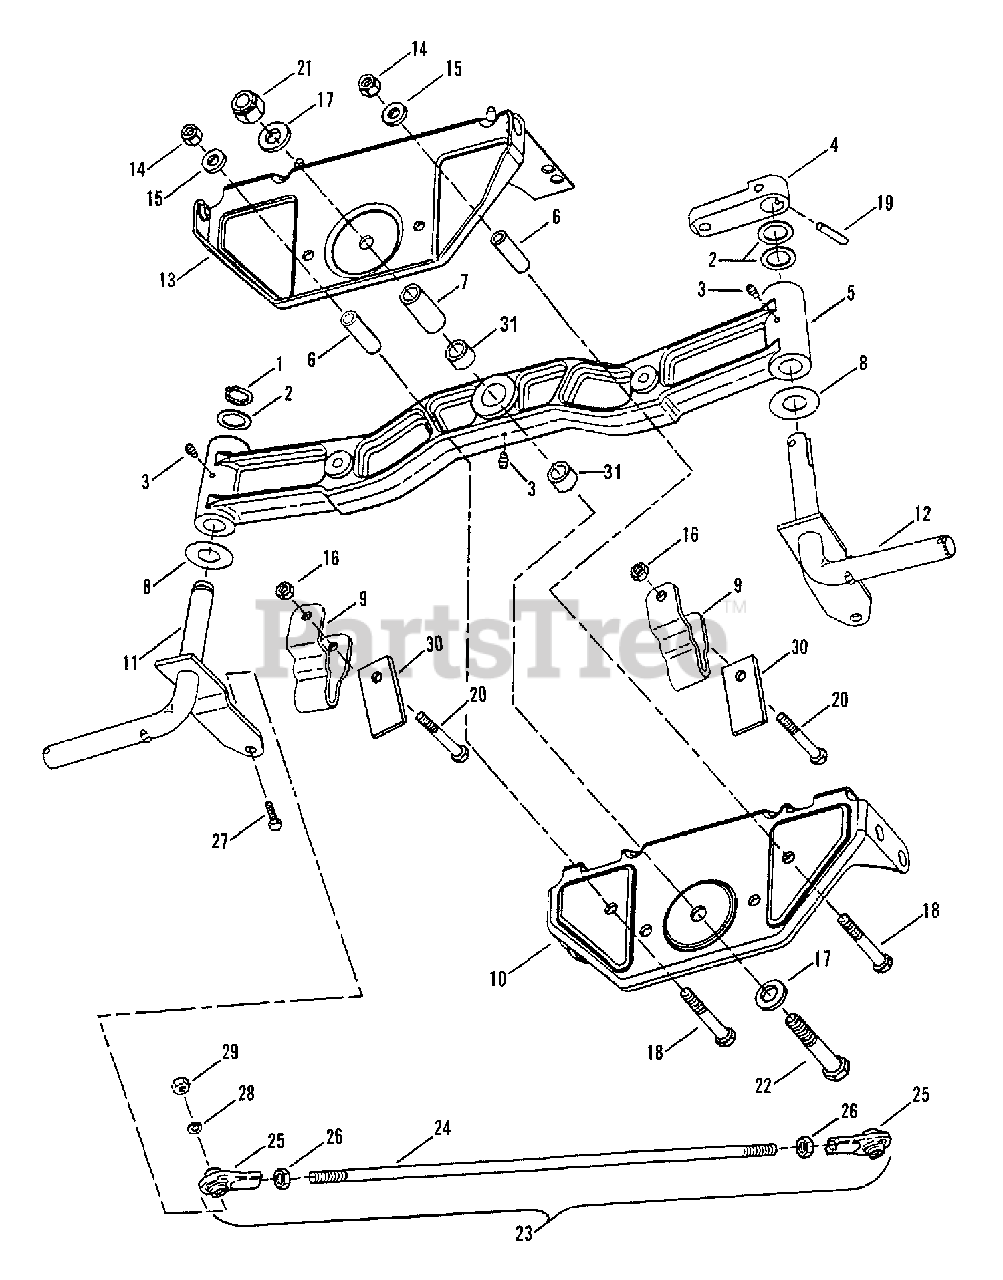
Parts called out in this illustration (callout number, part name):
1	RING, 5/8 External Retaining
2	WASHER, 49/64 x 1-1/8 x 1/16" Flat
3	FITTING, 3/16 Lube
4	ARM, Steering
5	AXLE, Cast
6	SPACER, 25/64 x 1/2 x 1-13/16"
7	SPACER, Center
8	WASHER, Thrust
9	BRACKET, Deck Hanger
10	BRACKET, Cast Axle (Rear)
11	WELDMENT, Right Hand Spindle Wheel (Short)
12	WELDMENT, Left Hand Spindle Wheel (Short)
13	ASSEMBLY, Cast Axle Front Bracket
14	NUT, 3/8-16 Hex Nyloc
15	WASHER, 3/8 x 5/64" Flat
16	NUT, 5/16-18 Hex Center Lock
17	WASHER, 1/2 x 3/32" Flat
18	SCREW, 3/8-16 x 2-3/4" Hex Head Cap, Grade 2
19	PIN, 1/4 x 1-1/4" Roll
20	SCREW, 5/16-18 x 2-3/4" Hex Head Cap, Grade 5
21	NUT, 1/2-13 Hex Nyloc
22	SCREW, 1/2-13 x 3" Hex Head Cap Grade 5
23	ASSEMBLY, Tie Rod
24	ROD, Steering Connector
25	BALL JOINT, 3/8-24
26	NUT, 3/8-24 Hex Jam
27	SCREW, 3/8-16 x 1-1/2" Hex Head Cap, Grade 5
28	WASHER, 3/8 Split Lock
29	NUT, 3/8-16 Hex, Grade 5
30	SPACER, Steering Stop
31	BUSHING, Sleeve
